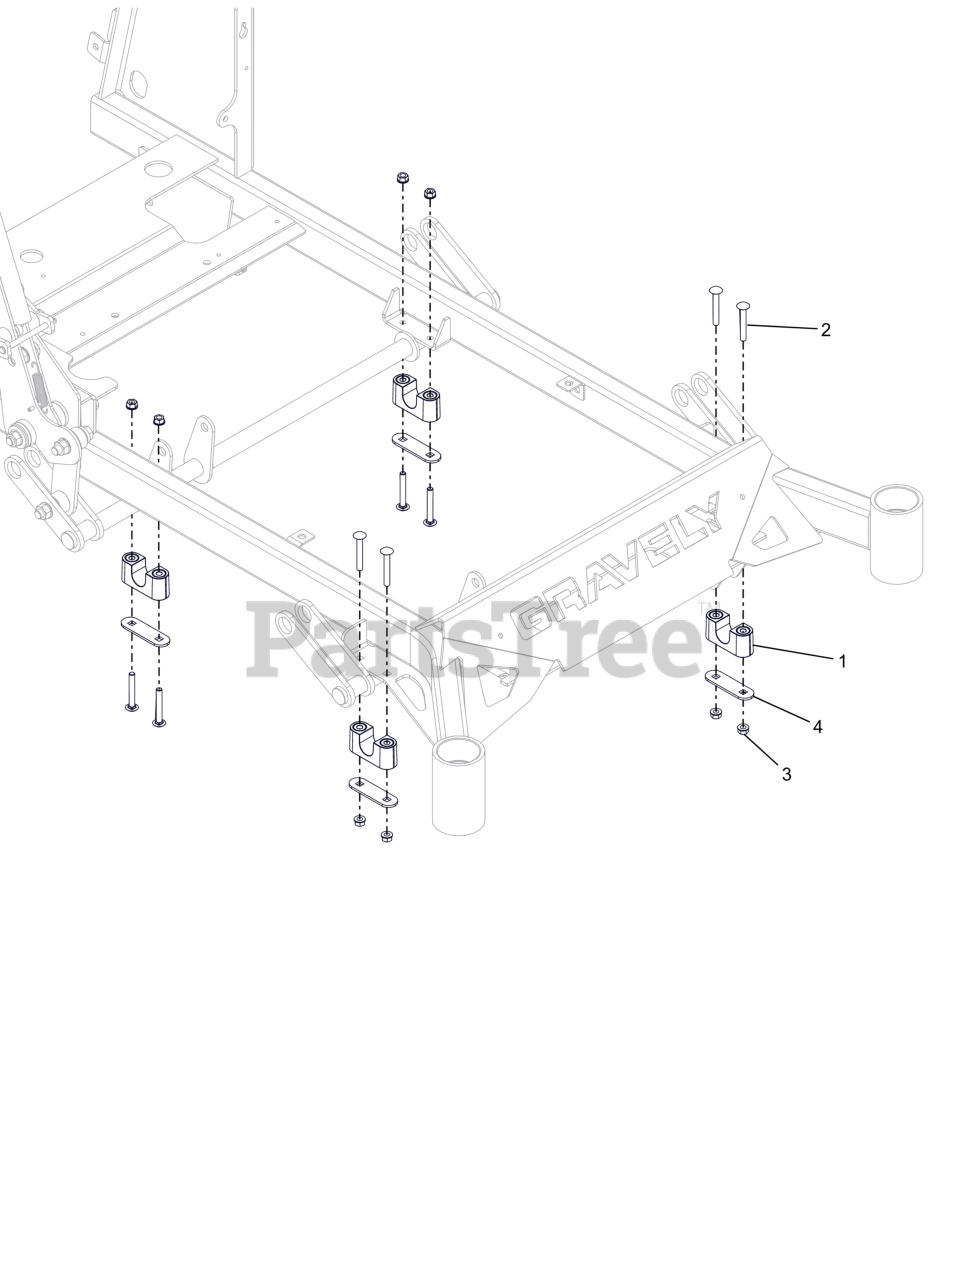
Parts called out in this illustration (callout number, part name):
1	ASM-BUSHING, DECK LIFT
2	BLT, RHSSN.31-18X2.25 G5 ZCC
3	NUT,LK-CTR-FLG .31-18 GF ZCC
4	PLATE, BEARING SUPPORT
